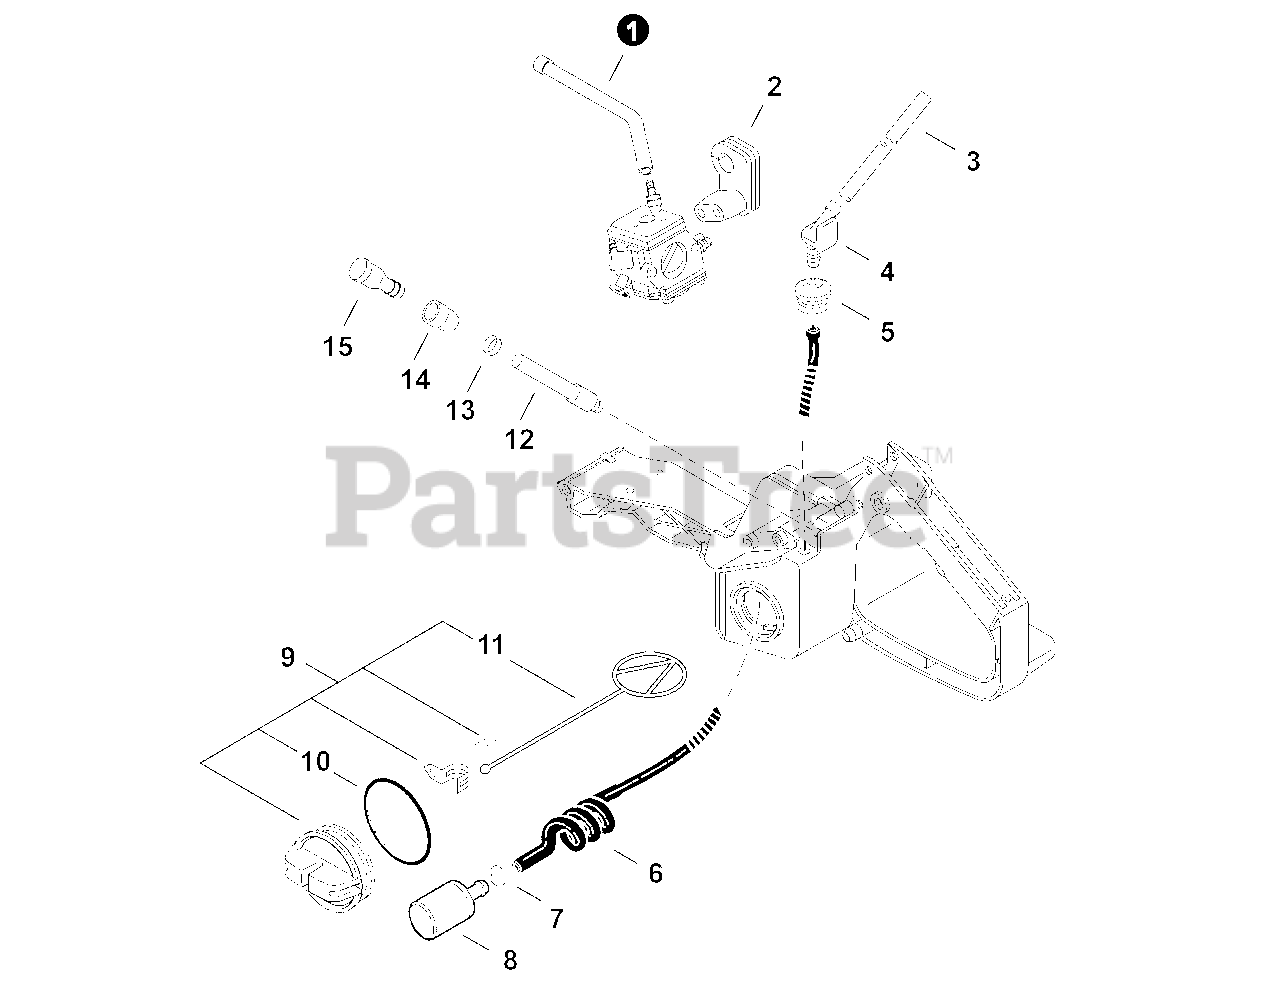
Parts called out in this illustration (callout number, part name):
1	PIPE, IMPULSE
2	GROMMET, NEEDLE
3	PIPE, FUEL 3×6×110
4	CONNECTOR, PIPE
5	GROMMET
6	PIPE, FUEL
7	CLIP Ø6.5 MM
8	FILTER, FUEL
9	CAP ASSY, FUEL
10	O-RING 29
11	CONNECTOR, CAP L= 60 MM
12	PIPE, VENT
13	CLIP Ø6.5 MM
14	HOLDER, VENT
15	VENT ASSY
